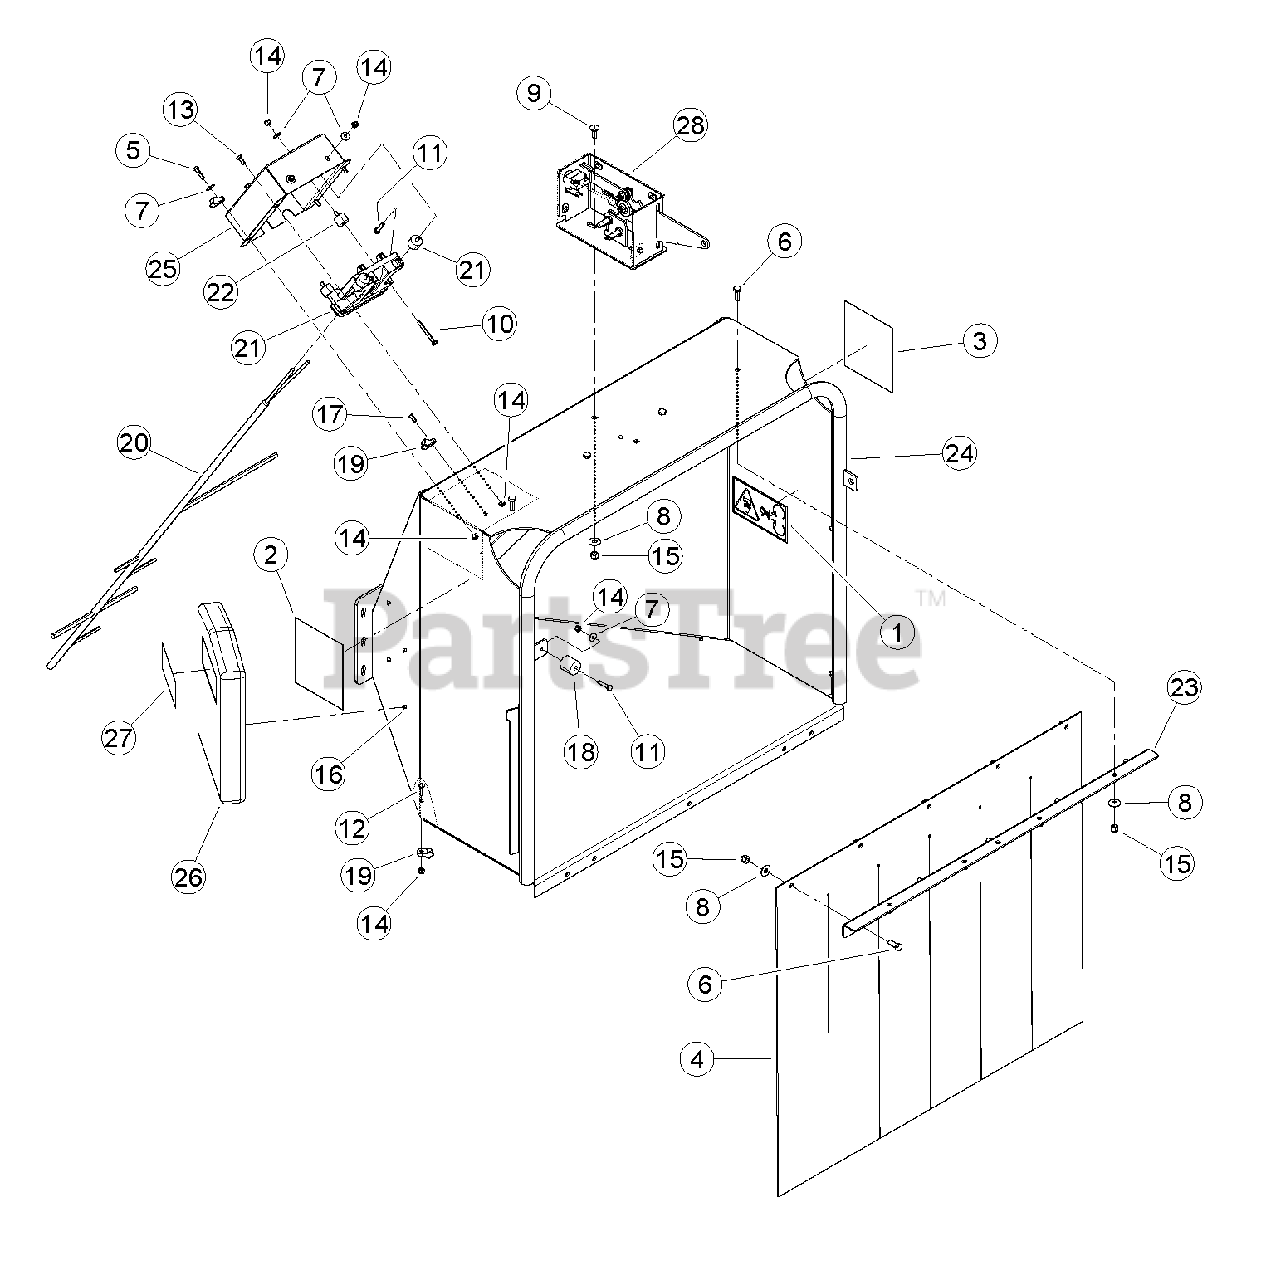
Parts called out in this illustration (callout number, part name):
1	DECAL, BLADE DANGER ISO
2	DECAL, FEED POSITION
3	DECAL, FEED POSITION
4	FLAP, CHUTE
5	BOLT, 1/4 X 1 HEX HD GR5 ZP
6	BOLT, 3/8 X 1 HEX HD GR5 ZP
7	WASHER, 1/4 FLAT ZP
8	WASHER, 3/8 FLAT ZP
9	BOLT, 3/8 X 1 CRG GR5 NC ZP
10	BOLT, 1/4 X 2-1/4 HEX HD GR5 ZP
11	BOLT, 1/4 X 1-1/4 HEX HD GR5 ZP
12	BOLT, 1/4 X 1 CRG GR5 NC ZP
13	BOLT, 1/4 X 5/8 HEX HD GR5 ZP
14	NUT, 1/4 NE NYLOCK ZP
15	NUT, 3/8 NE NYLOCK ZP
16	RIVET, AL BLIND 1/4 X 1/2 DOME HEAD
17	RIVET, AL BLIND 1/4 X 3/4 DOME HEAD
18	BUMPER, RECESSED RUBBER
19	CLAMP, CABLE MOUNT
20	HARNESS, 6" DIESEL PLUS 1 CONTROLLER
21	CONTROLLER, PLUS 1 CHIPPER
22	BUMPER, 1" OD W/1/4" STUD
23	SUPPORT, CHIPPER FLAP
24	WELDMENT, CHIPPER CHUTE
25	ENCLOSURE, PLUS 1 MOUNT
26	ASSEMBLY, MANUAL CONTAINER, SERVICE PART
27	DECAL, MUTILINGUAL MANUAL
28	ASSEMBLY, SWITCH BOX
